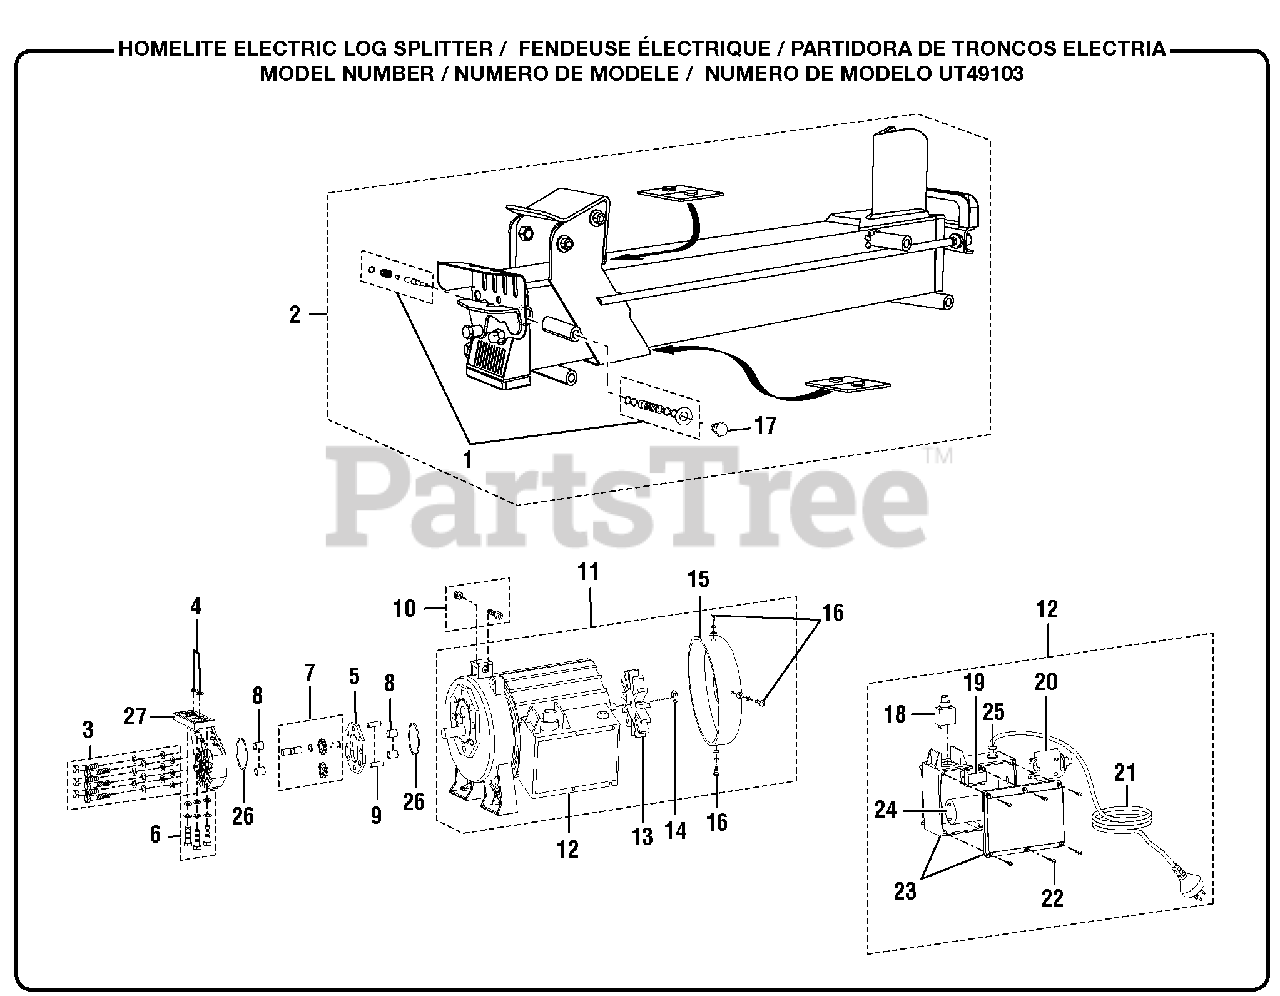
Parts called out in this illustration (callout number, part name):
1	Ram Valve Assembly
2	Main Body Assembly
3	Bolt Assembly
5	Gear Housing Plate
6	Bolt Assembly
7	Gear Assembly
10	Nut And Bolt Assembly
11	Motor Assembly
12	Switch Box Assembly
14	Retaining Ring
16	Screw (4 x 10 mm) w/Washers
19	Connection Terminal
20	Circuit Breaker
22	Screw (M2.9 x 12 mm)
23	Switch Box Assembly
25	Strain Relief
27	Gear Pump Cover
